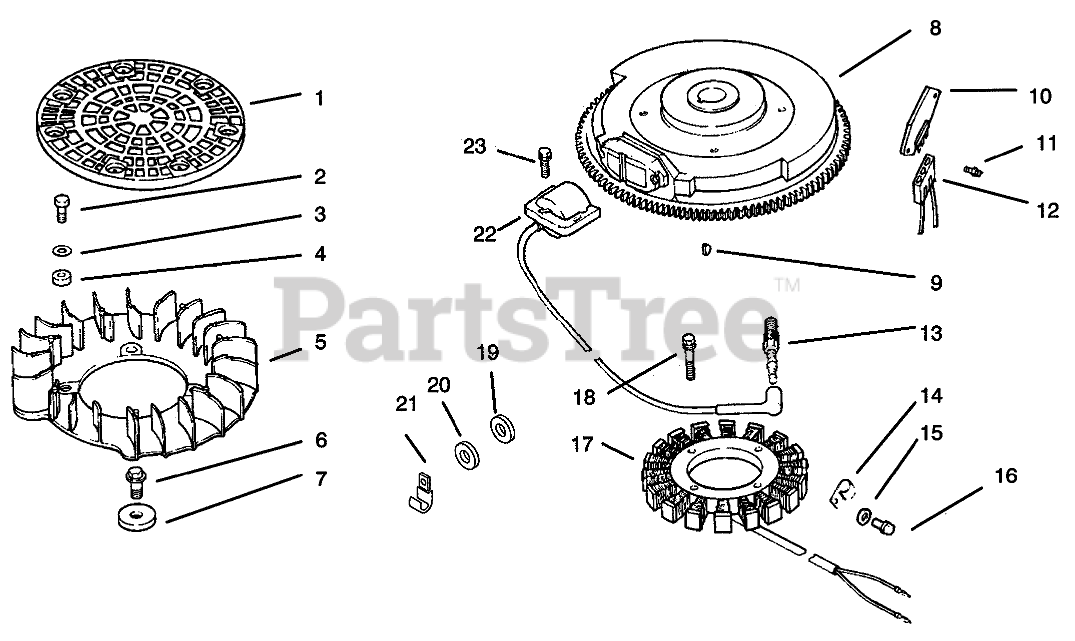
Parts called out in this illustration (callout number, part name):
1	Screen-Grass
2	Screw
3	Washer
4	Spacer-Fan
5	Fan
6	Screw
7	Spacer
8	Flywheel
9	Key
10	Rectifier-Regulator
11	Screw
12	Connector
13	Plug-Spark
14	Clip
15	Washer
16	Screw
17	Stator-15 Amp
18	Screw
19	Washer
20	Washer
21	Clip
22	Module-Ignition
23	Screw
